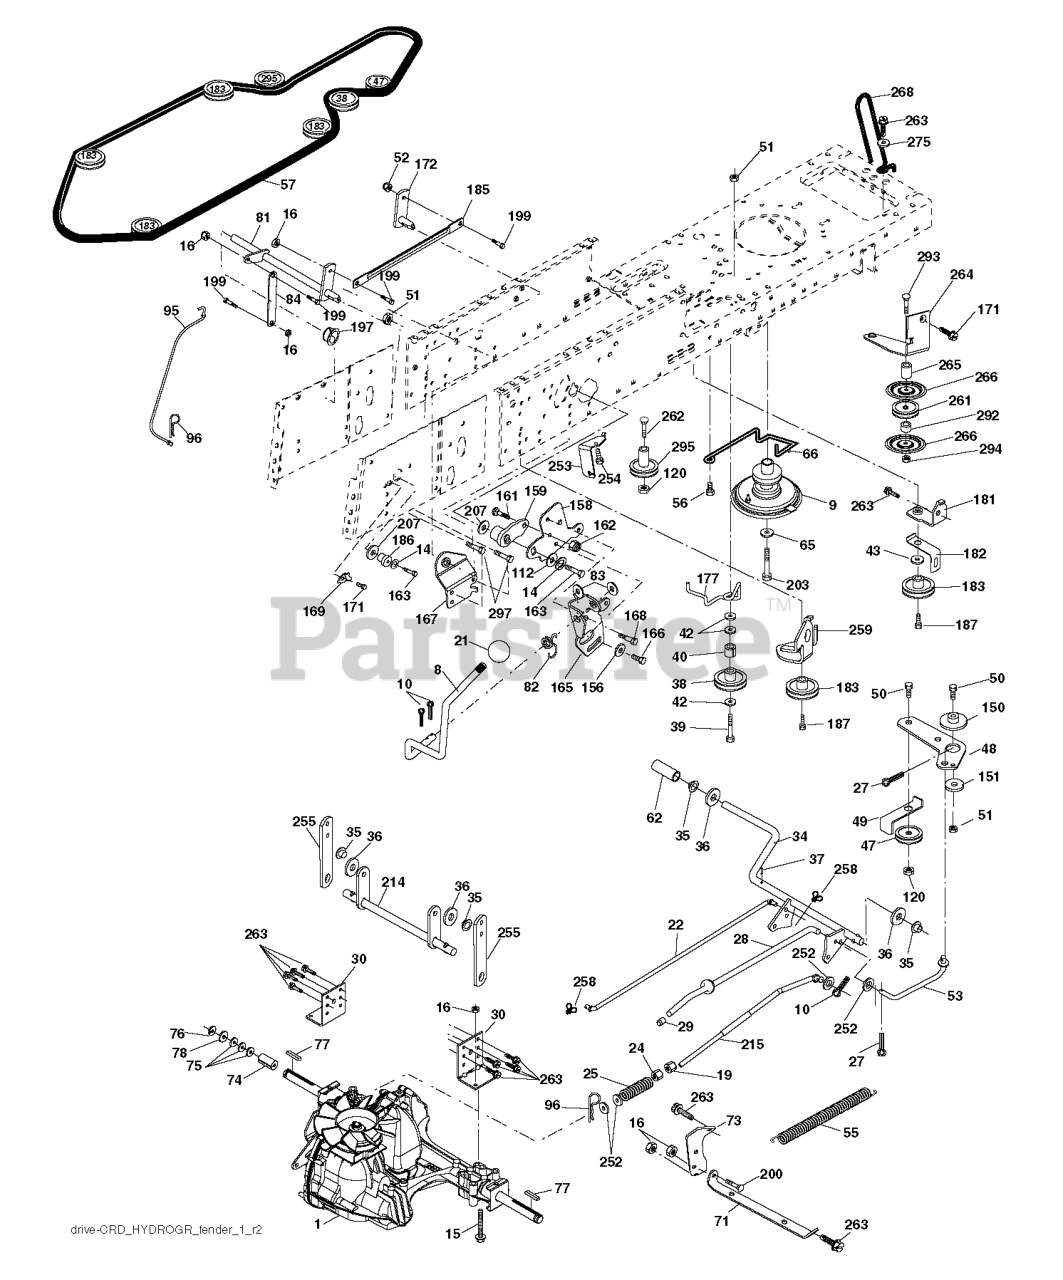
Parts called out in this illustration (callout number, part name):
8	ROD SHIFT FENDER ADJUST LT
10	PIN COTTER
14	LOCKWASHER
15	BOLT HEX 5/16-18 GR 5
16	NUT.71038.31-18.HEX.NYLOCK
19	NUT
21	KNOB T (1/2-HOLE)
22	ROD
24	NUT
25	SPRING BRAKE ROD
27	COTTER PIN
28	ROD, PARKING BRAKE
29	PLUNGER CAP
30	BRKT, TRNSXLE MNT 20"
34	SHAFT, FOOT PEDAL
35	BEARING.NYLON
36	WASHER LT
37	DRIVE PIN
38	PULLEY.FLAT
42	WASHER
43	WASHER T
47	IDLER PULLEY
48	BELLCRANK, CLUTCH
49	RETAIN BELT
50	BOLT.3/8-16X1.50
52	LOCKNUT
53	LINK.CLUTCH.7.66.2005
55	SPRING, RETURN LT
56	SCREW.3/8-16
57	V-BELT 113"
62	PEDAL COVER T
65	LOCKWASHER
66	KEEPER BELT ENGINE
71	STRAP TORQUE LH HYDRO
73	STRAP TORQUE RH HYDRO
74	SPACER AXLE
77	SQUARE KEY
81	ASM.CROSS.SHAFT.REAR.CRD.0510
82	SHIFT SPRING
83	WASHER
84	LINK.PNT.TRANSAXLE.0510.CRD
95	LINK
96	RETAINER M
112	WASHER LT
120	NUT LOCK FLG 3/8-16 UNC
150	BUSHING.BELLCRANK.GRD.DR
151	WASHER 12/32X2X10GA
156	WASHER.SRRTD.5/16
158	BRACKET.SHIFT.MOUNT
161	BOLT
162	NUT.CROWNLOCK.1/4
163	BOLT
165	BRACKET.PIVOT.LEVER
166	CAPSCREW.HXHD.FLG.5/16-18X.625
167	BRACKET.SUPT.SHIFT.CRD
168	BOLT.SHOULDER.5/16-18X
169	PLATE.FASTENING.CROSS.SHAFT
171	SCREW LT
172	LINK
181	BRACKET
182	BELT GUIDE
183	PULLEY.V-IDLER.
185	LINK
186	HUB.TAPERED.ROUND.CRD
187	BOLT.5/16-18X1.25
197	NYLINER SNAP 5/8" ID
199	BOLT SHOULDER 5/16-18 UNC
200	BOLT
203	BOLT.HEX.7/16-20 X 5
207	WASHER NYL
214	LEVER
215	ROD
252	WASHER
254	SCREW 3/8-16X1
255	SHAFT
258	CLIP RETAINER
259	BRACKET
261	FLAT IDLER PULLEY
263	SCREW, 3/8-16X3/4
264	BRACKET.IDLER.CHASS.NORAM.2010
266	PROTECTOR
268	GUARD MUFFLER
275	WASHER
292	SPACER
293	BOLT.RDHD SQNK 3/8-16 X 3-1/2
294	NUT.HEX.3/8-16
295	PULLEY IDLER COMPOSITE
297	SCREW LT.3/8-46X5/8
